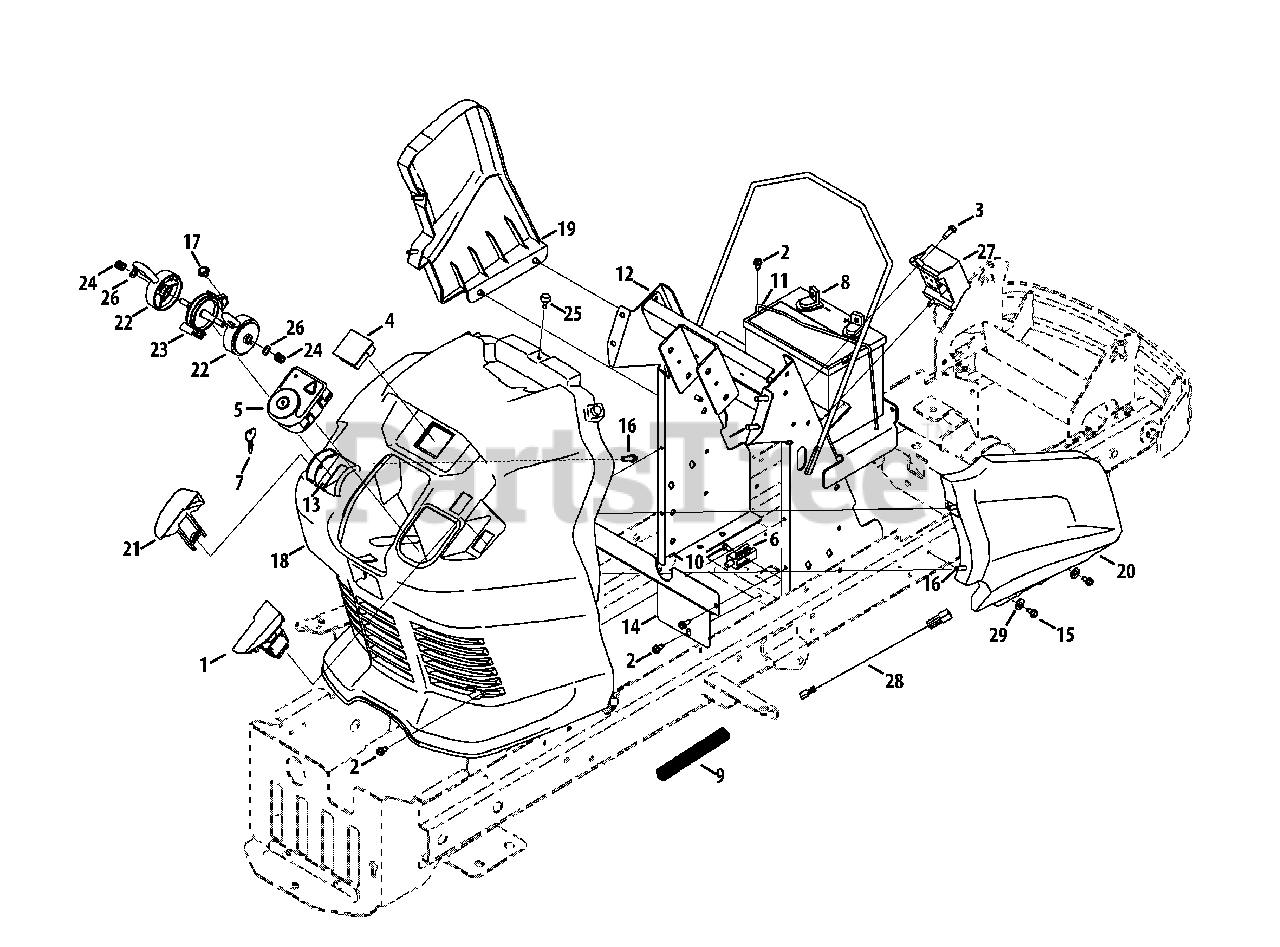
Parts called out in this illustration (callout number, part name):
1	PTO Lever
2	Hex Washer Screw, 1/4-20 x .500
3	Hex Washer Screw, 1/4-20 x .750
4	Hour/Service Minder Indicator Meter
5	Key Switch
6	Interlock Switch
7	Key Assembly
10	Shoulder Screw, #10-32 x .500
11	Battery Strap
13	Throttle Control Mount Bracket
14	Engine Air Upper Shield
15	Hex Washer Screw, 5/16-18 x .750
16	Hex Washer Screw, 5/16-14 x 1.00
17	Hex Washer Screw, #10-16 x .375
18	Dash
19	LH Dash Panel
20	RH Dash Panel
21	Cruise/Brake Lever
22	Choke/Throttle Control
23	Choke/Throttle Index Disc
24	Compression Spring, .50 x .50
25	Bumper, .62 x .3
26	Flat Washer, .344 x .620 x .033
27	Wire Harness
28	Reverse Jumper Harness
29	Flat Washer, .406 x .875 x .059
